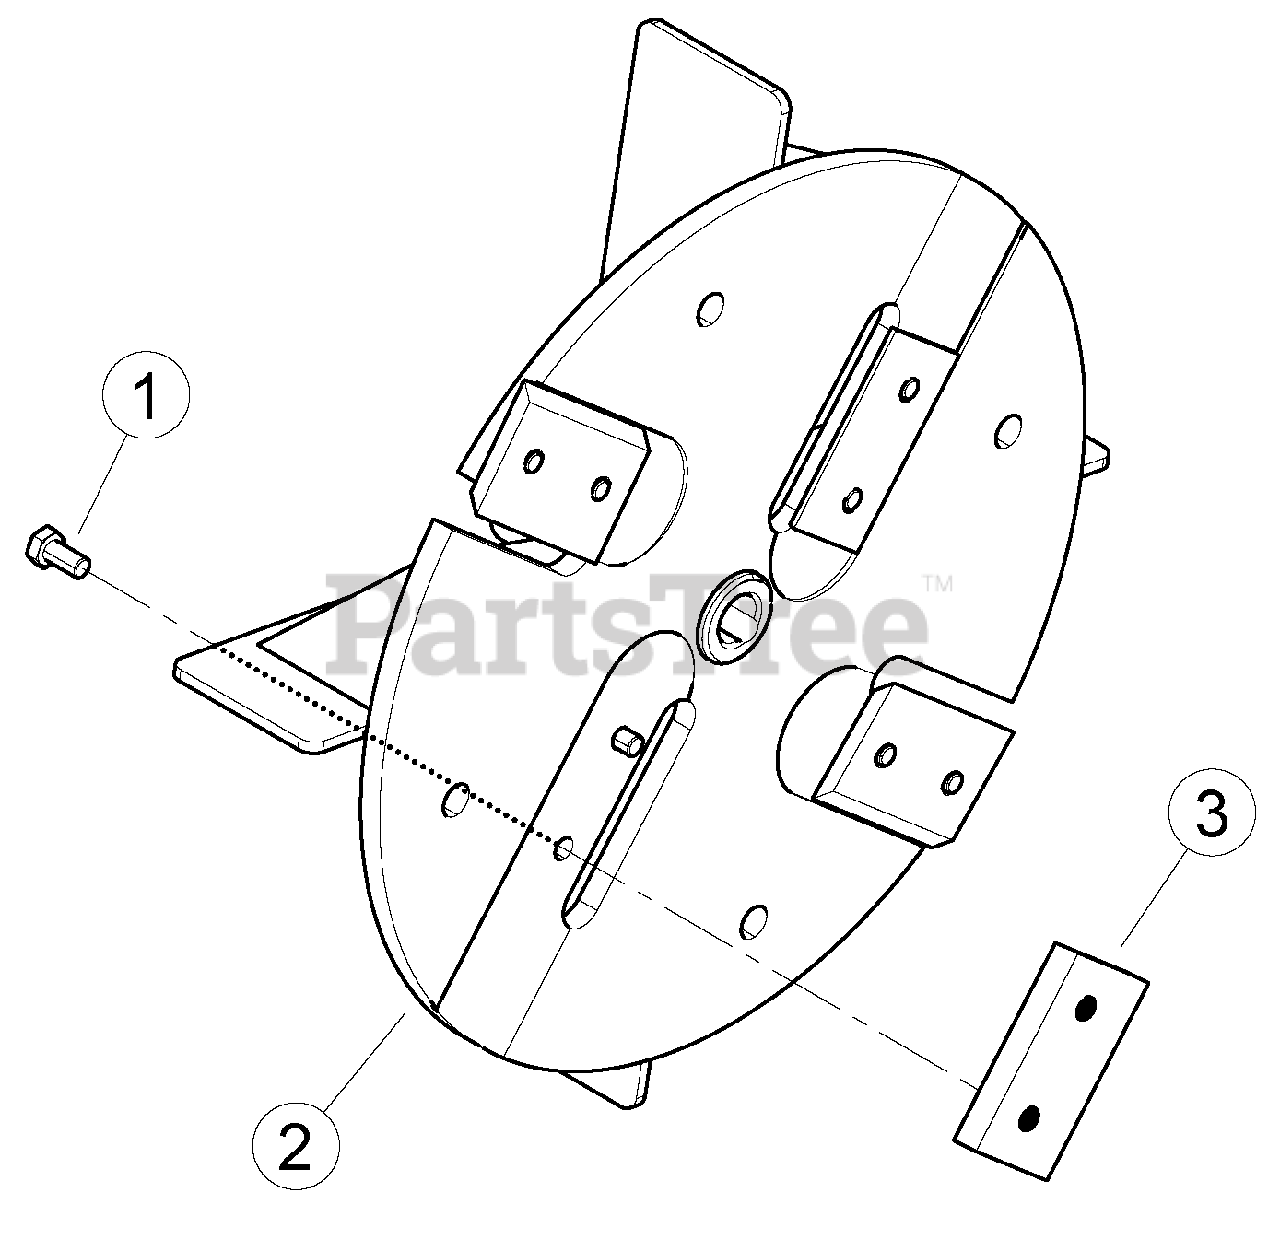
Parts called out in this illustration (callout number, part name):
1	BOLT, 5/16-18 X 5/8" G8 HCS PATCH Z
2	WELDMENT, CHIPPER ROTOR
3	KIT, CHOPPER BLADE
